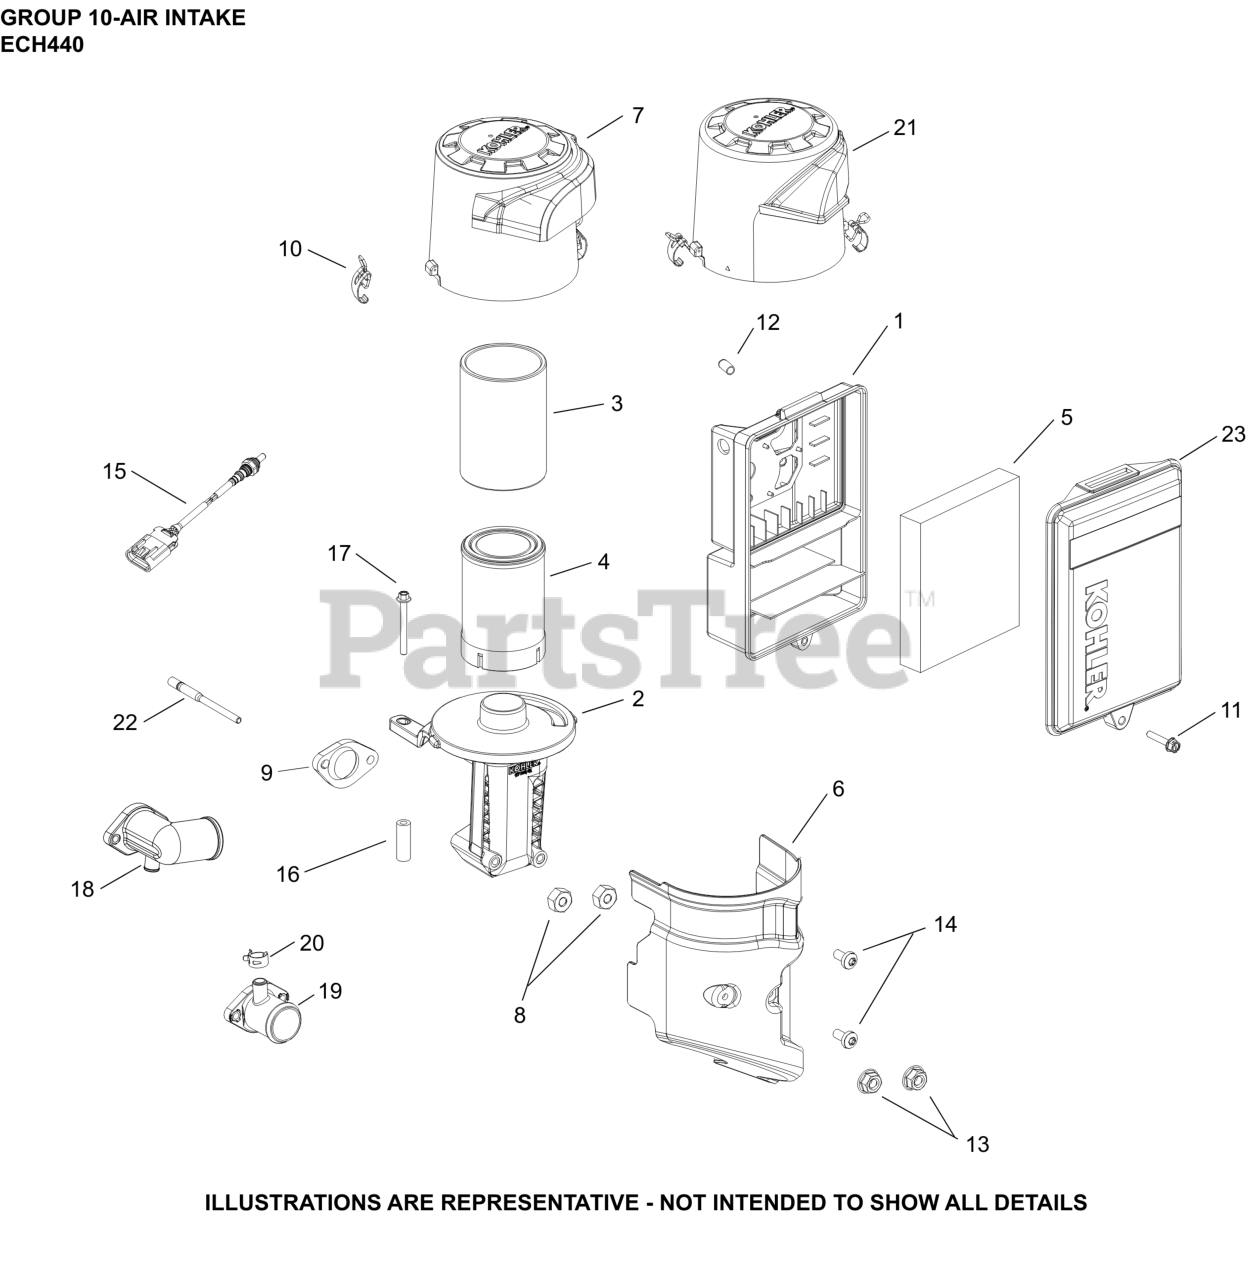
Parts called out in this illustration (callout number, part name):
9	INSULATOR THROTTLE BODY
13	NUT, HEX FLANGE LOCK (M6)
18	ELBOW, AIR INLET
20	CLAMP, BREATHER HOSE
